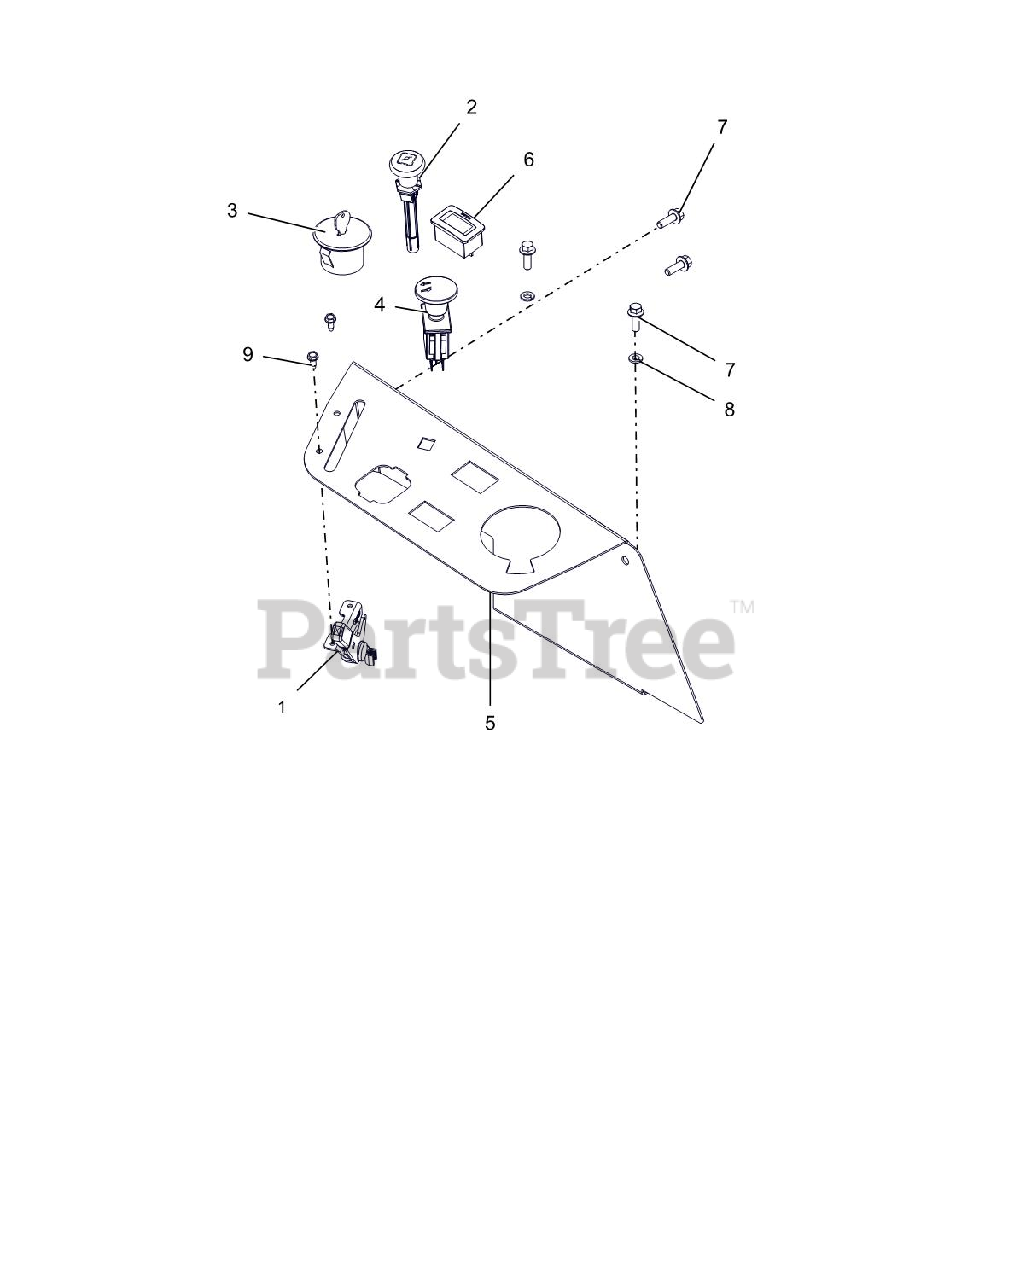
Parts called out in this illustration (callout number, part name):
1	CABLE - THROTTLE CONTROL
2	CABLE - CHOKE, SNAP-IN
3	KEYSWITCH-IGNITION 4 POS
3	KEYSWITCH-IGNITION 3 POS
4	SWITCH, CLUTCH (YELLOW)
5	PANEL, RIGHT SIDE FENDER MOUNT
6	HOUR METER
7	BLT,HEX-FLG .25-20X.75 G5 BFP
8	@WSHR-LK .25X.062 REG YWZC
9	@SCR-TAP 10-24X.50 HWH TR YWZC
